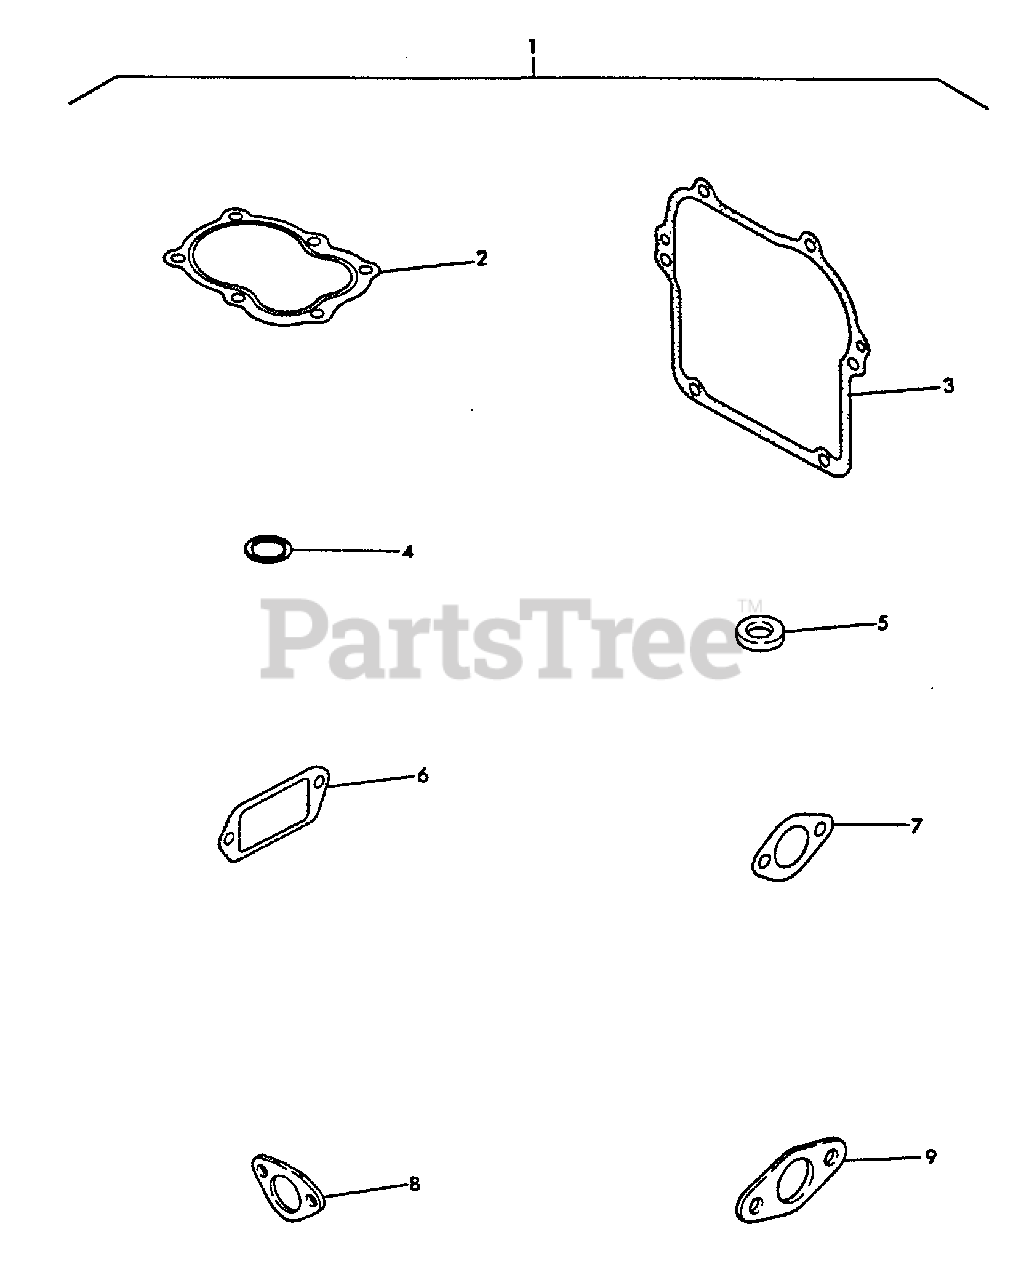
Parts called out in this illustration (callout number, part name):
1	GASKET KIT
2	GASKET, CYLINDER
3	GASKET, CRANKCASE
4	O-RING - 18
5	GASKET
6	GASKET, BREATHER
7	GASKET, INTAKE
8	GASKET, EXHAUST
9	GASKET, INTAKE
